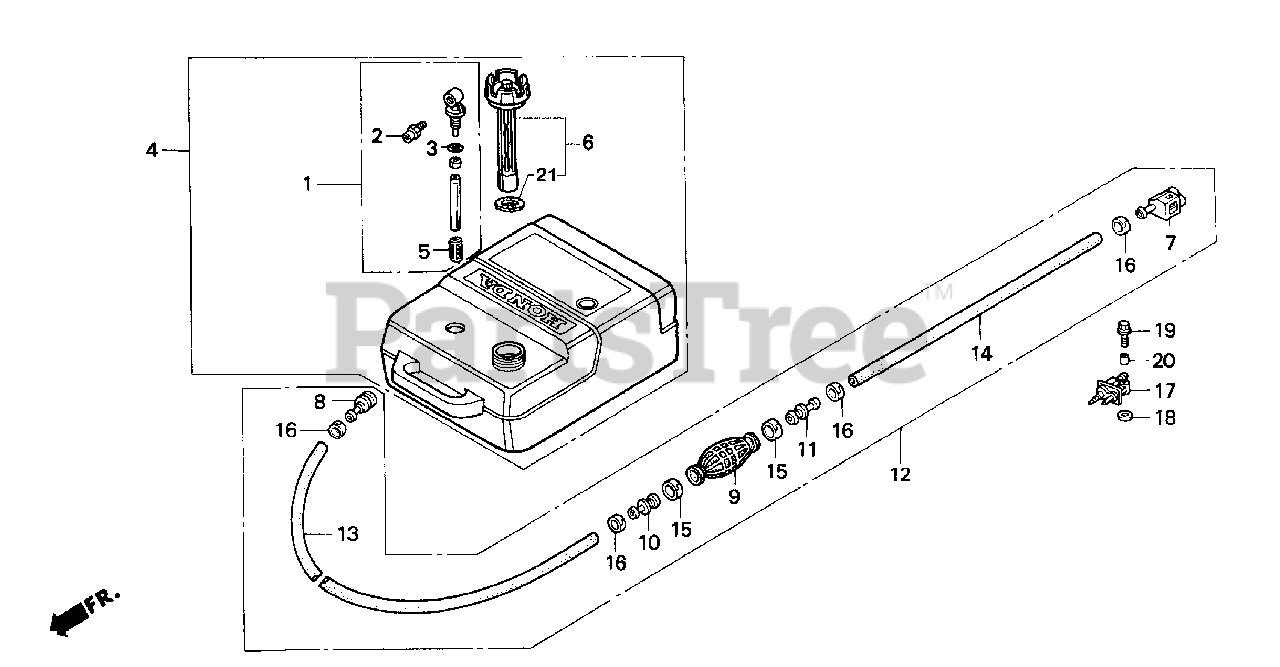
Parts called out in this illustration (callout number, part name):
1	JOINT ASSY., FUEL
2	FITTING, QUICK DISCONNECT
3	O-RING
4	TANK ASSY., FUEL
4	TANK, FUEL (25 LITER)
5	FILTER, FUEL
6	CAP, FUEL FILLER
7	CONNECTOR SET, FUEL
7	CONNECTOR ASSY. A, FUEL
8	CONNECTOR, FUEL
9	PRIMER BULB
10	VALVE, IN.
11	VALVE, OUTLET
12	TUBE ASSY., FUEL
13	TUBE, FUEL LONG (7.5X2000)
14	TUBE, FUEL SHORT
15	BAND, TUBE CLIP (20MM)
16	BAND, TUBE CLIP (12.5MM)
17	CONNECTOR SET, FUEL
17	CONNECTOR ASSY. B, FUEL
18	WASHER, PIVOT
19	BOLT, FLANGE (6X20)
20	COLLAR, DISTANCE (6MM)
21	GASKET, FUEL CAP
